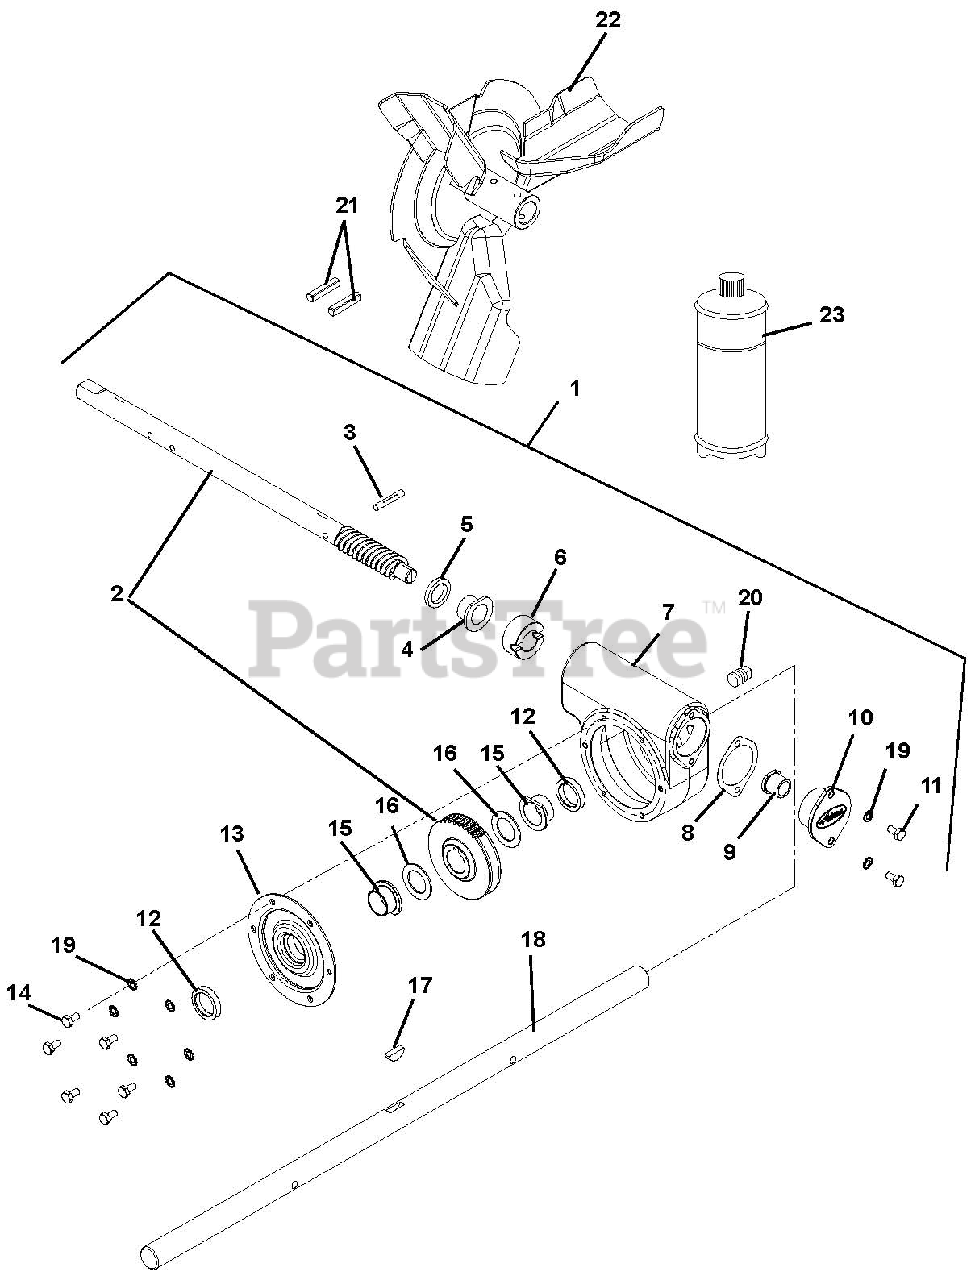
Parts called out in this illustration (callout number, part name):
1	GEAR CASE, 26" CAST IRON
1	GEAR CASE, 28" CAST IRON
1	GEAR CASE, 32" CAST IRON
1	GEAR CASE, 36" CAST IRON
2	ASSY, WORM SHAFT & GEAR
3	PIN-GRV .250X1.50 TP E
4	BSHG-FLG .876 X 1.500 X .750
5	SEAL-OIL .875X1.25X.188
6	THRUST COLLAR, .875" ID
7	GEARCASE, CAST IRON-MACHINED
8	GASKET, FRONT - CAST IRON
9	BSHG-FLG .629 X 1.000 X .750
10	COVER, FRONT-CI GEARCASE
11	@BLT-HEX .25-20X.50 GR5 YWZC
12	SEAL-OIL 1.000X1.375X.25
13	COVER, CI GEARCASE W/GASKET
14	BLT-HEX .25-20X.38 YWZC GR5
15	BSHG-FLG 1.003X1.5X.625
16	WSHR-FL-STL 1.010X1.505X.062YZ
17	KEY-WDRF .25X.875 HRD #A
18	SHAFT, RAKE-26"
18	SHAFT, RAKE-28"
18	SHAFT, RAKE-32"
18	SHAFT, RAKE-36"
19	@WSHR-LK-EXT.262X.502X.026YWZC
20	PIPE PLUG, 1/4 NPT
21	PIN-ROLL .250X1.75
22	IMPELLER, 3 BLADE-14"
23	ARIENS L3 LUBE, 8 OZ BOTTLE
